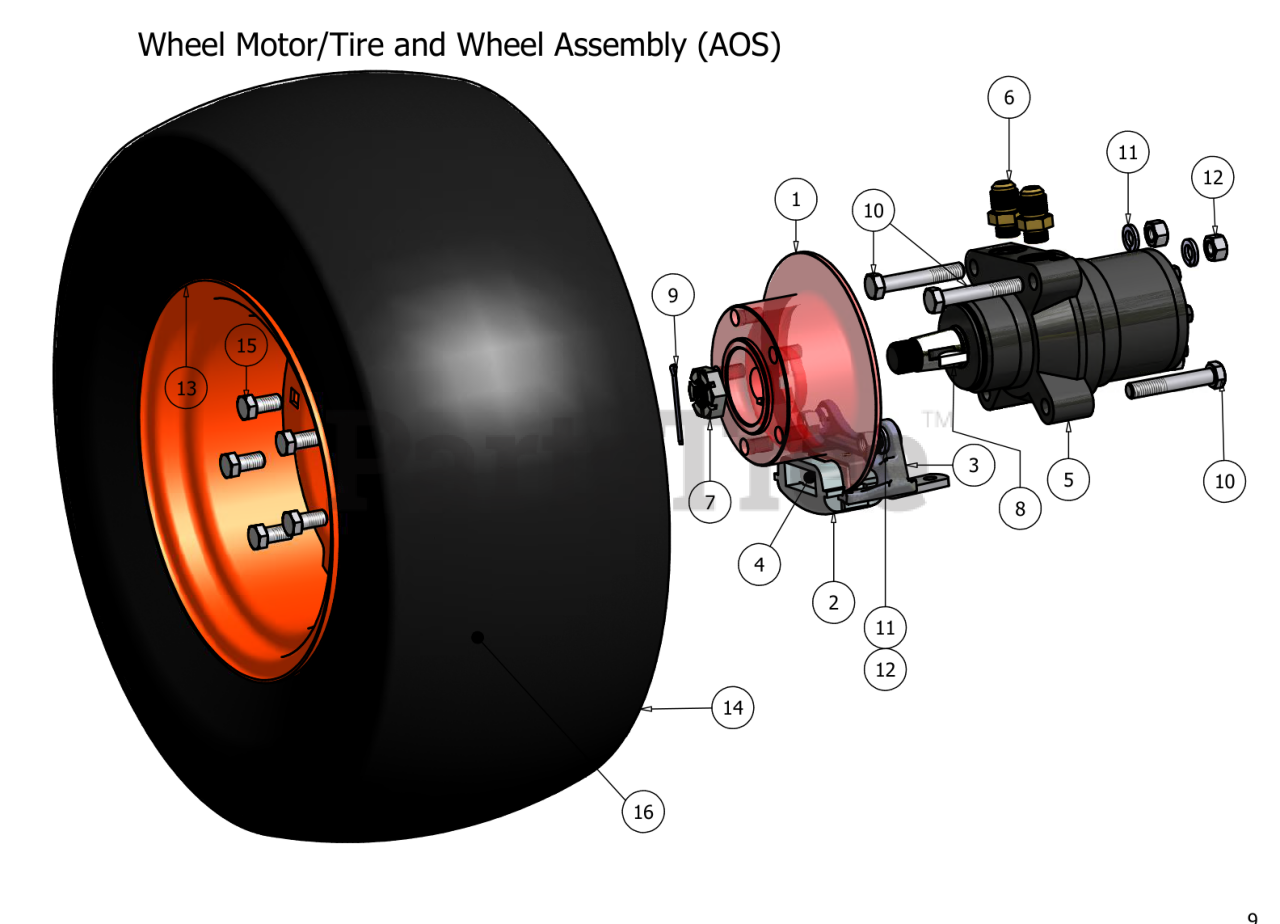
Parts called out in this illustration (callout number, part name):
1	Brake Disc
2	Right Brake Assembly
2	Left Brake Assembly
3	Brake Casting
4	Brake Pads
5	Right Wheel Motor
5	Left Wheel Motor
6	3" Hydraulic Fitting
7	Castle Nut
8	Woodruff Key
9	1/8" x 2 1/4" Cotter #8
10	1/2" x 3" Hex Bolt
11	1/2" Lock Washer
12	1/2" Hex Nut
13	12" Rim AOS Models -
14	26x12-12 Tire - AOS Models
15	1/2" x 1" Lug Bolt (Fine Thread)
16	26 x 12-12 Tire and Wheel Assembly
